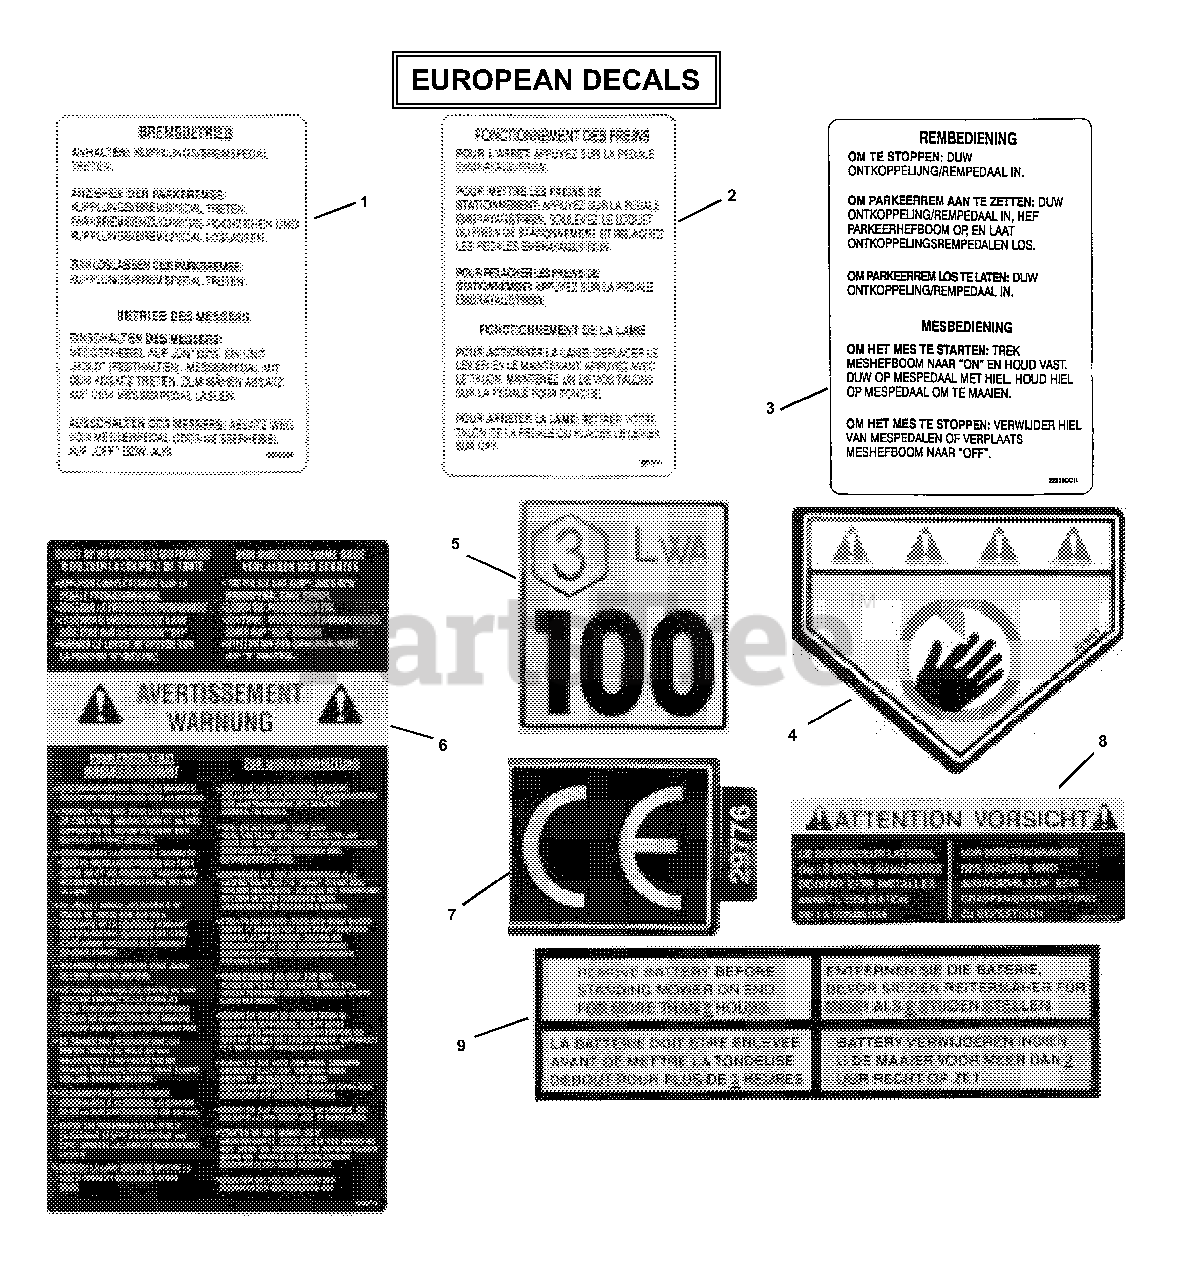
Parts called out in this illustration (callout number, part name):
1	DECAL, Brake Operation (German)
2	DECAL, Brake Operation (French)
3	DECAL, Brake Operation (Dutch)
4	DECAL, WARNING
5	DECAL, European Noise Control
6	DECAL, SAFETY Instruction (German & French)
7	DECAL, European Community
8	DECAL, Deflector (German & French)
9	DECAL, Battery Storage
